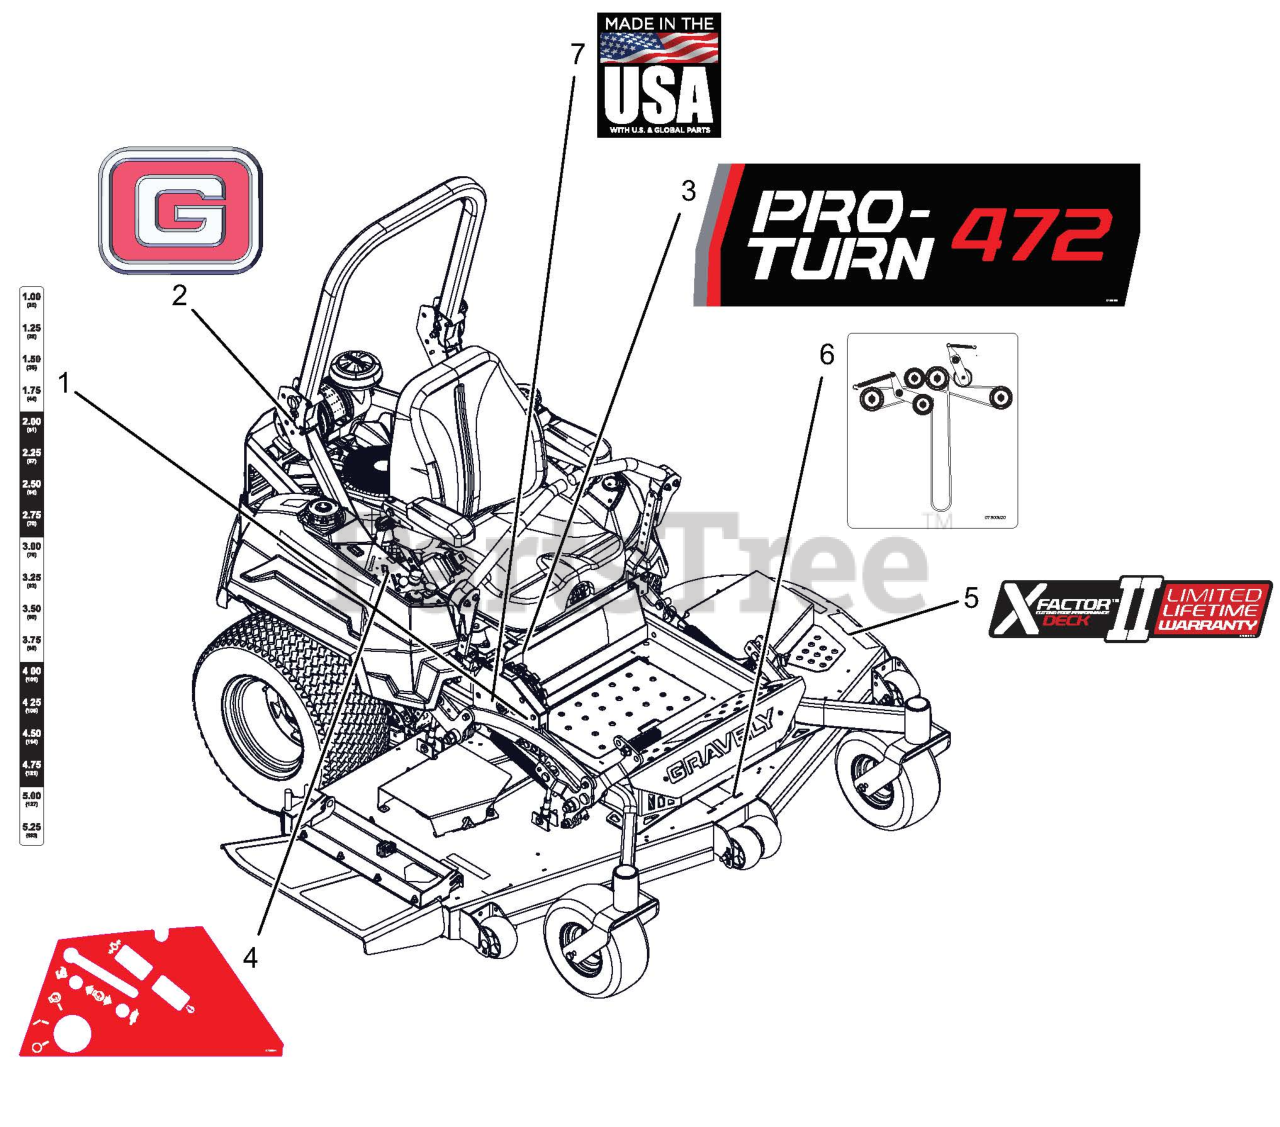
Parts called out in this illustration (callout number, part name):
1	DECAL, PT400 HEIGHT OF CUT
2	DECAL, GRAVELY BRAND
3	DECAL, PRO-TURN 472
4	DECAL, EFI CONTROL PANEL
5	DECAL, X-FACTOR DECK
6	DCL,BELT ROUTE-RH BK-SIDE IDLR
7	DECAL, MADE IN USA
